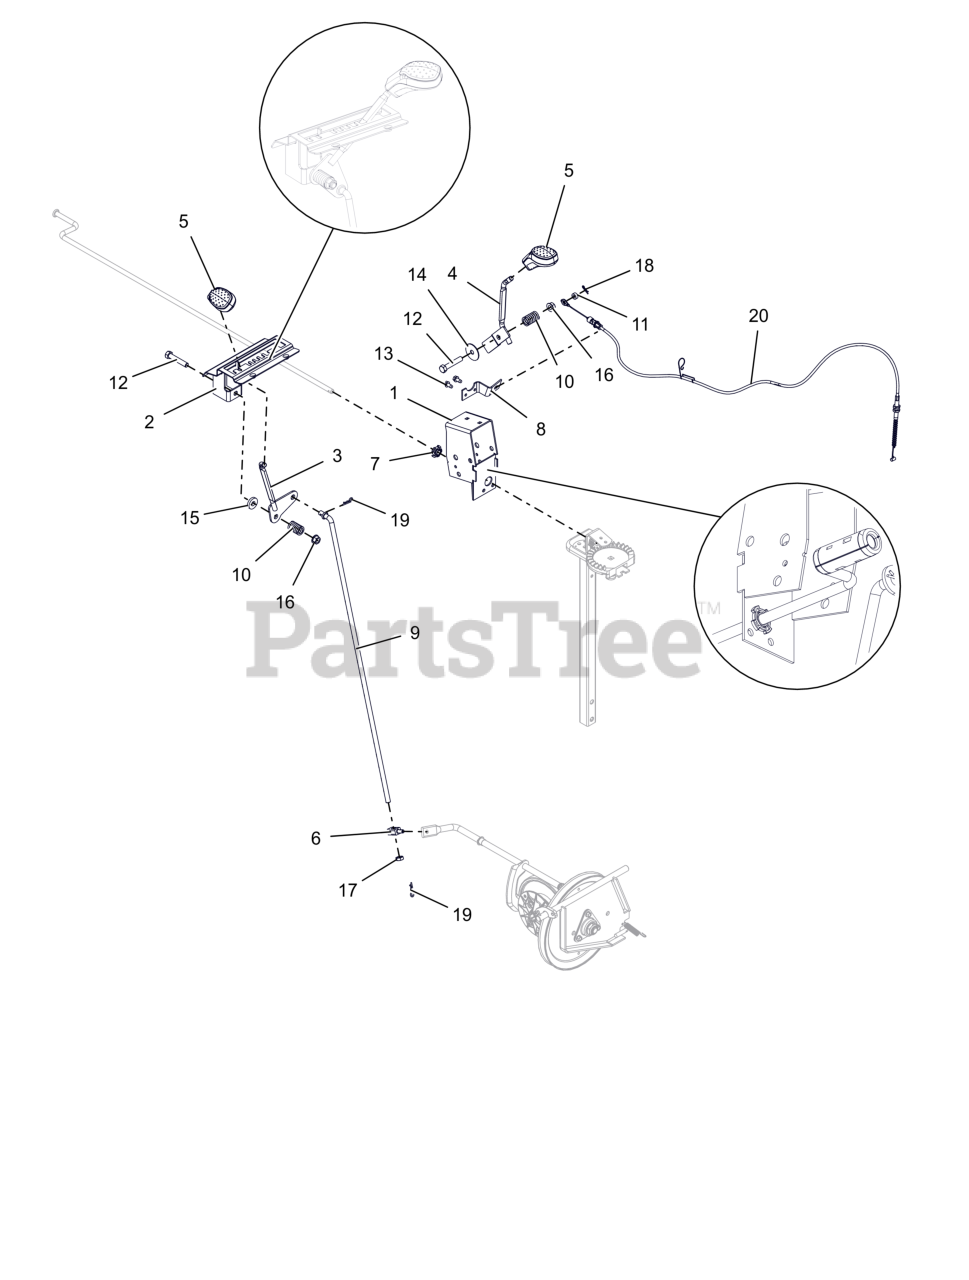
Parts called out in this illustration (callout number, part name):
1	WELDMENT, BRACKET INTERLOCK
2	WELDMENT, DETENT PLATE-COMPACT
3	LEVER, CONTROL-SHIFT(WELDMENT)
4	WELDMENT,SM DASH DEFL CONTROL
5	KNOB, CONTROL, DASH
6	PIVOT,SHIFT ROD .375-16(TRUNN)
7	CRANK BUSHING, NYLON CHUTE BK
8	ANCHOR, DEFLECTOR CABLE
9	ROD, SHIFT - COMPACT
10	SG-COMP .125X.781X1.250
11	BSHG-SLV .265X.500X.219
12	BLT,HEX .38-16X2.00 G5 ZCC
13	SCR-TAP .25-20X.50 HWH ZCC
14	WSHR,FLT .380X1.50X.062 ZCC
15	WSHR, FLT .406X1.00X.188 ZCC
16	NUT-LK-TOP-FLG .38-16 ZC120
17	NUT-JAM .375-16 G2 ZCC
18	PIN, HAIR #178 .06X.77 ZCC
19	PIN, HAIR #213 .08X1.19 ZCC
20	CABLE, DEFLECTOR - COMPACT
